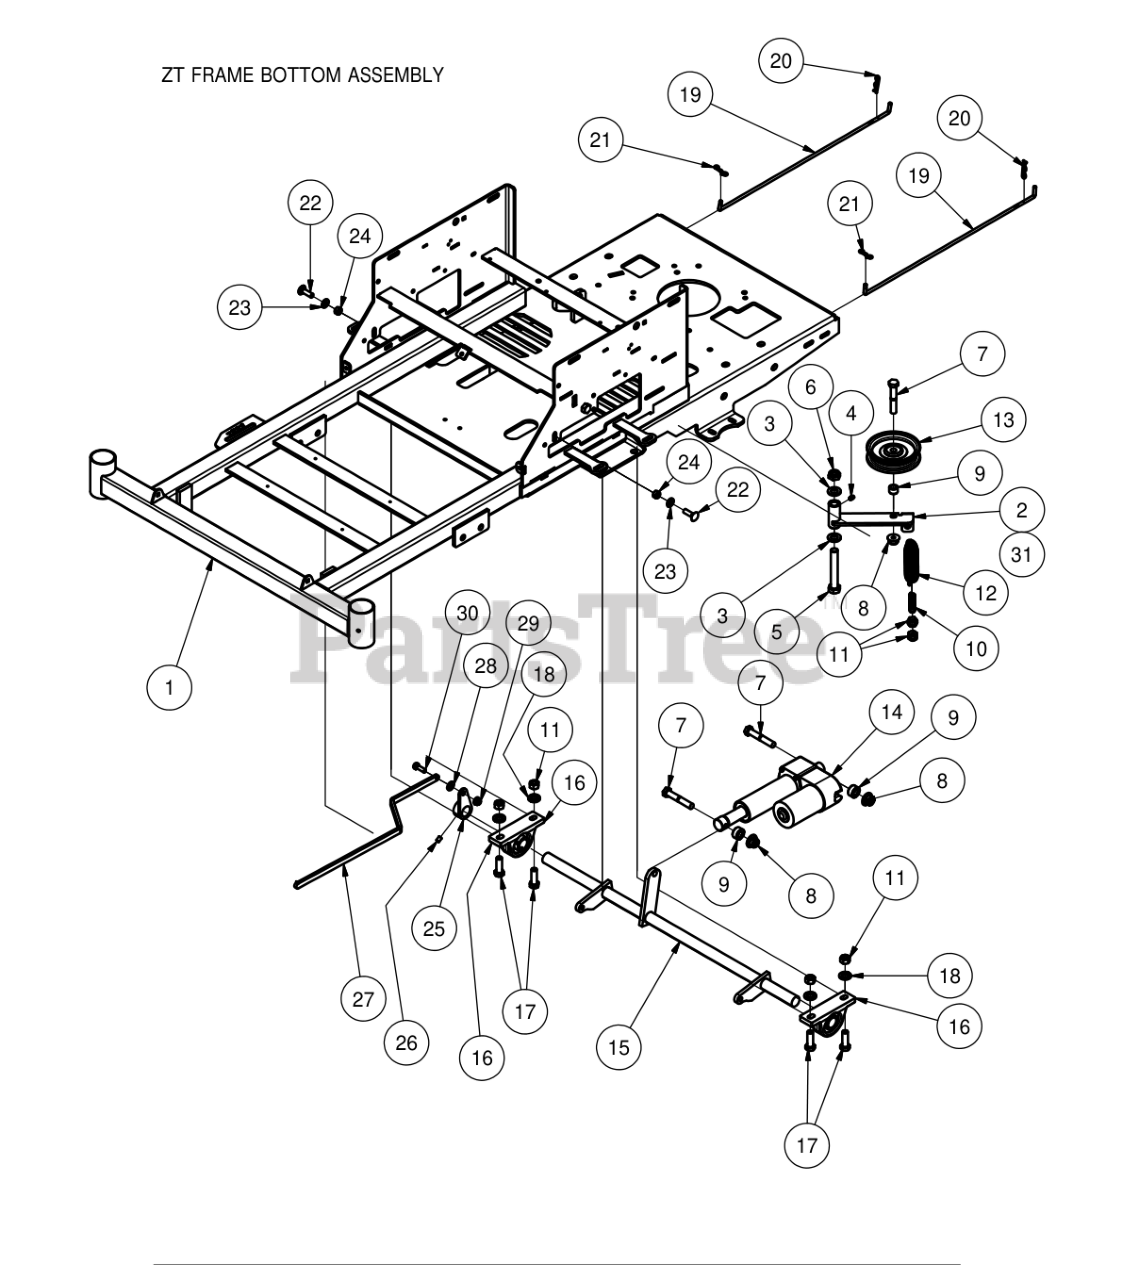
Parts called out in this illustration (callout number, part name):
2	Pump Idler Bracket
3	.630 ID Plastic Washer
4	1/4" Press in Grease Fitting
5	5/8" x 4" Hex Bolt
6	5/8" Nylock (1/2 Jam)
7	1/2-13 x 2-3/4 GR 5 Bolt Zinc
8	1/2-13 Nylon Flange Nut
9	1/2 Set Collar
10	All Thread-Pump Idler Tensioner
11	1/2" Hex Nut
12	2009 Deck/Pump Idler Spring
13	4 3/4" Idler Pulley
15	Actuator Bar-ZT
16	pillow block 2bolt sealmaster
17	1/2" x 1 1/2" Hex Bolt
18	1/2" Lock Washer Zinc
19	ZT Neutral level rod 2011
20	Neutral Rod Clip
22	3/8" x 1 1/4" Carriage Bolt
23	3/8" Flat Washer
24	3/8" Hex Nut
25	Height Indicator Lever
26	5/16 Set Screw
27	Height Indicator Bar
28	.360 ID Plastic Washer
29	5/16" Nylock Flange Nut
30	5/16" x 1" Bolt
31	Pump Idler Assembly (2,4,7,8,9,13)
